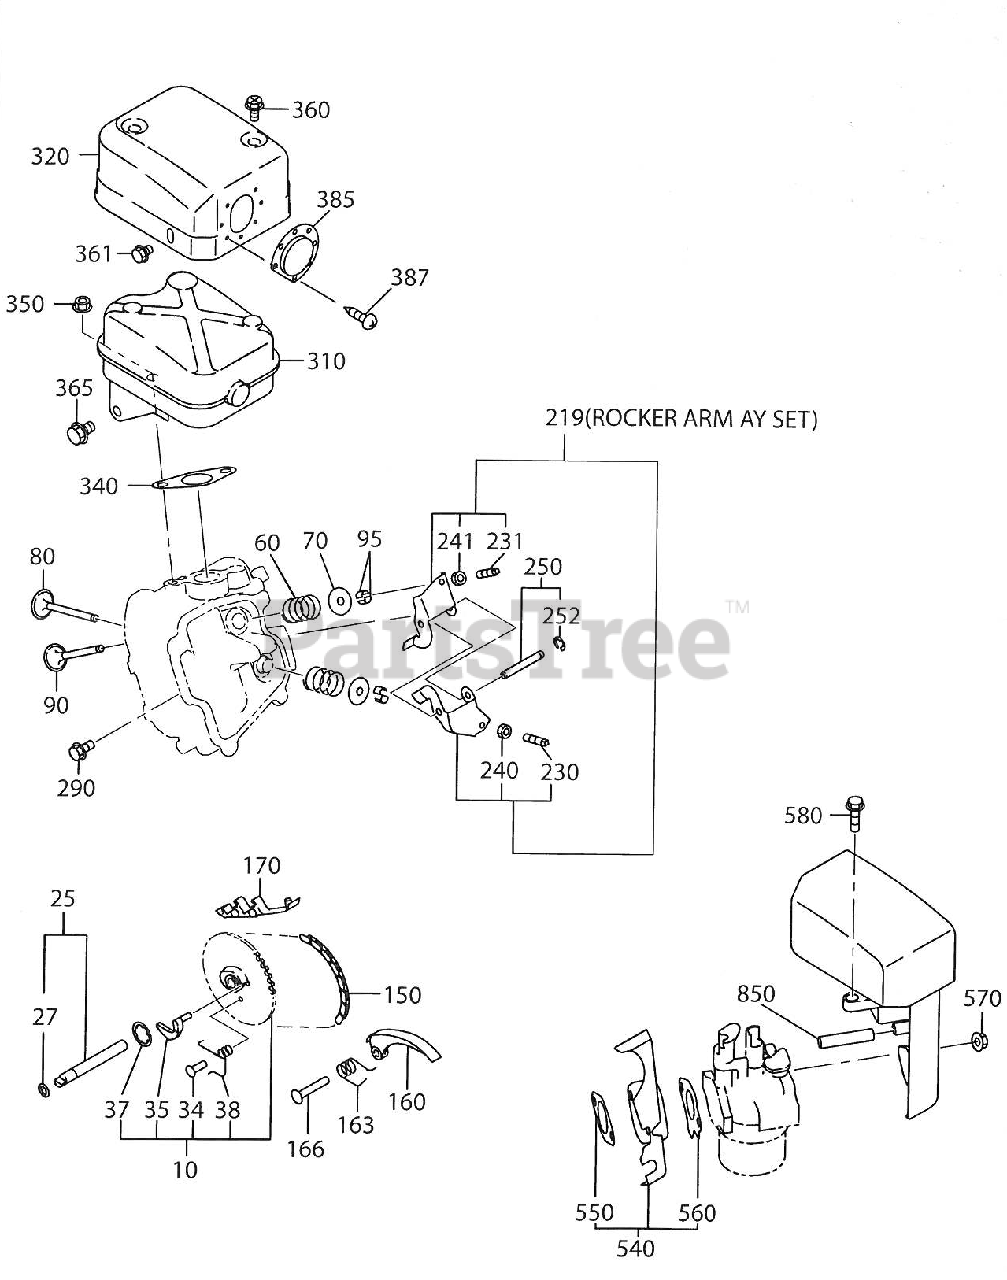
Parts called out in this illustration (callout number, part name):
25	PIN CP, CAMSHAFT
70	SPRING RETAINER
150	TIMING CHAIN CP
163	SPRING, TENTIONER
166	PIN, TENTIONER
250	PIN CP, ROCKER
320	MUFFLER COVER CP
340	GASKET, MUFFLER
550	GASKET 2, INSULATOR
560	GASKET 1, INSULATOR
